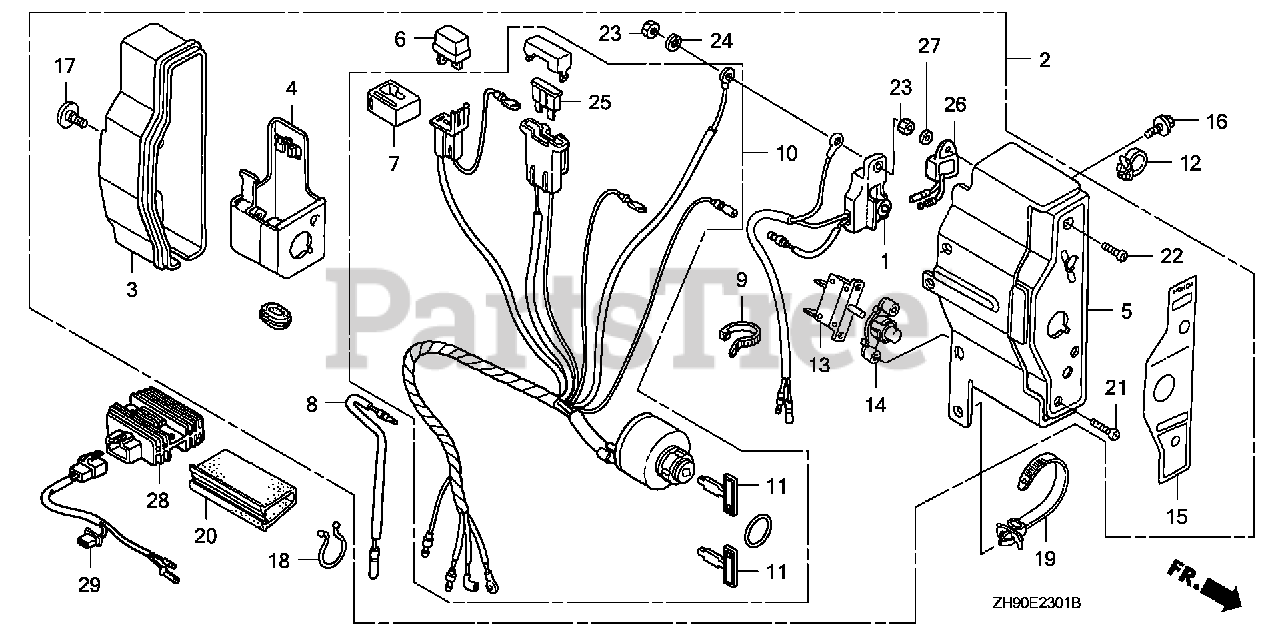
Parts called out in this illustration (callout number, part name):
2	BOX ASSY., CONTROL (3A) *NH1* (EXP-ALERT) (BLACK)
2	BOX ASSY., CONTROL (3A) *R280* (EXP-ALERT) (POWER RED)
3	CASE, CONTROL
4	BRACKET, CASE MOUNTING
5	PANEL, CONTROL *NH1* (BLACK)
5	PANEL, CONTROL *R280* (POWER RED)
6	RECTIFIER ASSY., SILICON (SHINDENGEN)
7	SUSPENSION, CONNECTOR
8	SUB-WIRE HARNESS
9	BAND
10	SWITCH ASSY., COMBINATION (3A-CHARGE)
11	KEY
12	HOLDER, STOP SWITCH WIRE Use up to Engine SN 2056819.
13	PROTECTOR, CIRCUIT (3.5A)
14	LENS ASSY., PROTECTOR
15	MARK, CONTROL BOX (EXP)
16	BOLT, FLANGE (6X12) (CT200)
17	SCREW, SPECIAL (6X12)
18	CLIP, PURSE LOCK
19	STRAP, CABLE (118MM) *NH1L* (Honda Code 1170653). (BLACK)
20	TUBE, FASTENER (30)
21	SCREW, PAN (3X12)
22	SCREW, PAN (4X12)
23	NUT, HEX. (4MM)
24	WASHER, SPRING (4MM)
25	FUSE, BLADE (15A)
26	ALERT UNIT, OIL
27	WASHER, PLAIN (4MM)
